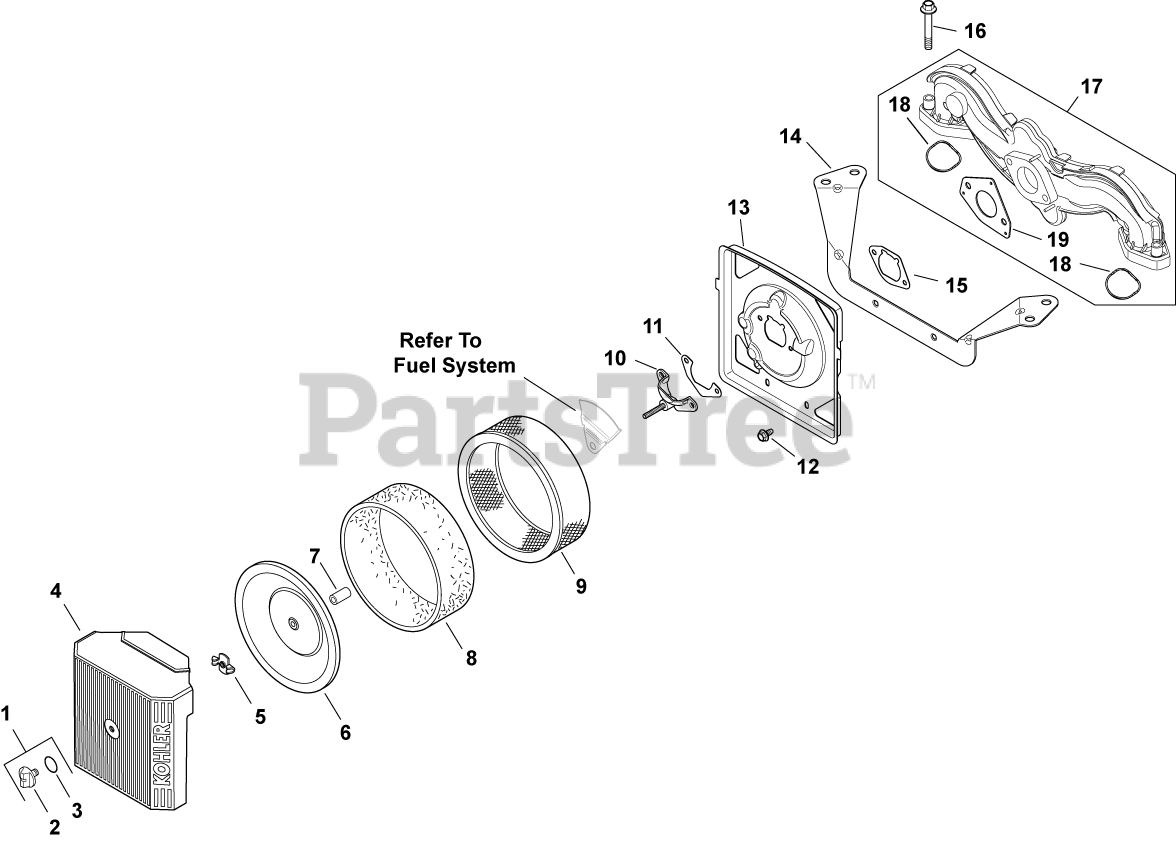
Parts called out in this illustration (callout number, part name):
1	KIT, KNOB W/SEAL
2	KNOB, COVER
4	COVER, AIR CLEANER
5	NUT, WING
6	COVER, INNER AIR CLEANER
7	SEAL, BREATHER
8	PRE-CLEANER (HIGH)
9	ELEMENT, AIR FILTER (HIGH) - Also available Retail Packaged 24 883 03-S1 Air Filter Kit
10	CUP, FUEL SPITBACK W/O NIPPLE
11	GASKET, FUEL SPITBACK CUP
12	SCREW, FLG THD FRM M5X.8X10
13	BASE, AIR CLEANER-USE 24 094 82-S
14	BRACKET, AIR CLEANER BASE
15	GASKET, AIR CLEANER BASE
16	SCREW, FLG M6X1.0X40
17	MANIFOLD, INTAKE - PLASTIC-USE 24 164 91
18	O-RING, INTAKE PORT
19	GASKET, CARBURETOR
2410909-S	CUP, SPITBACK W/STUD-USE 24 109 25-S
